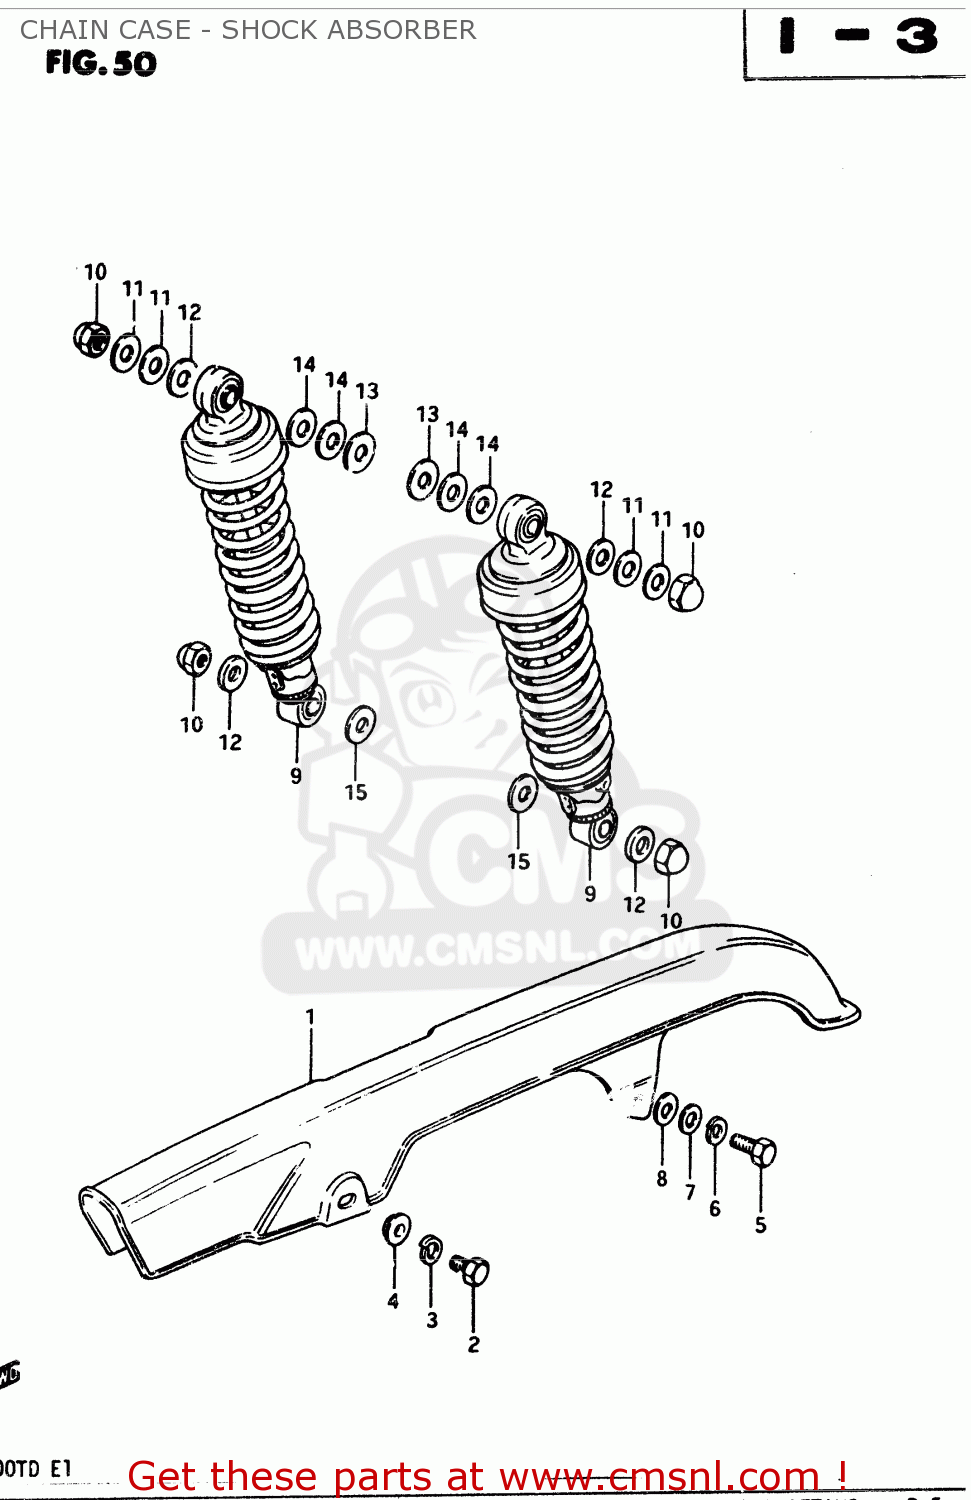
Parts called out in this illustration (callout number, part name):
1	CASE,CHAIN
2	BOLT
3	LOCK WASHER
4	WASHER,LOCK
5	BOLT
6	LOCK WASHER
7	WASHER
8	WASHER(6.5X18X1)
9	ABSORBER ASSEMBLY,REAR SHOCK
10	NUT, LOWER LH
11	WASHER(10.5X24X3.2)
12	WASHER
13	WASHER (12.5X24X3.2)
14	WASHER
15	WASHER (12.5X24X1.6)
